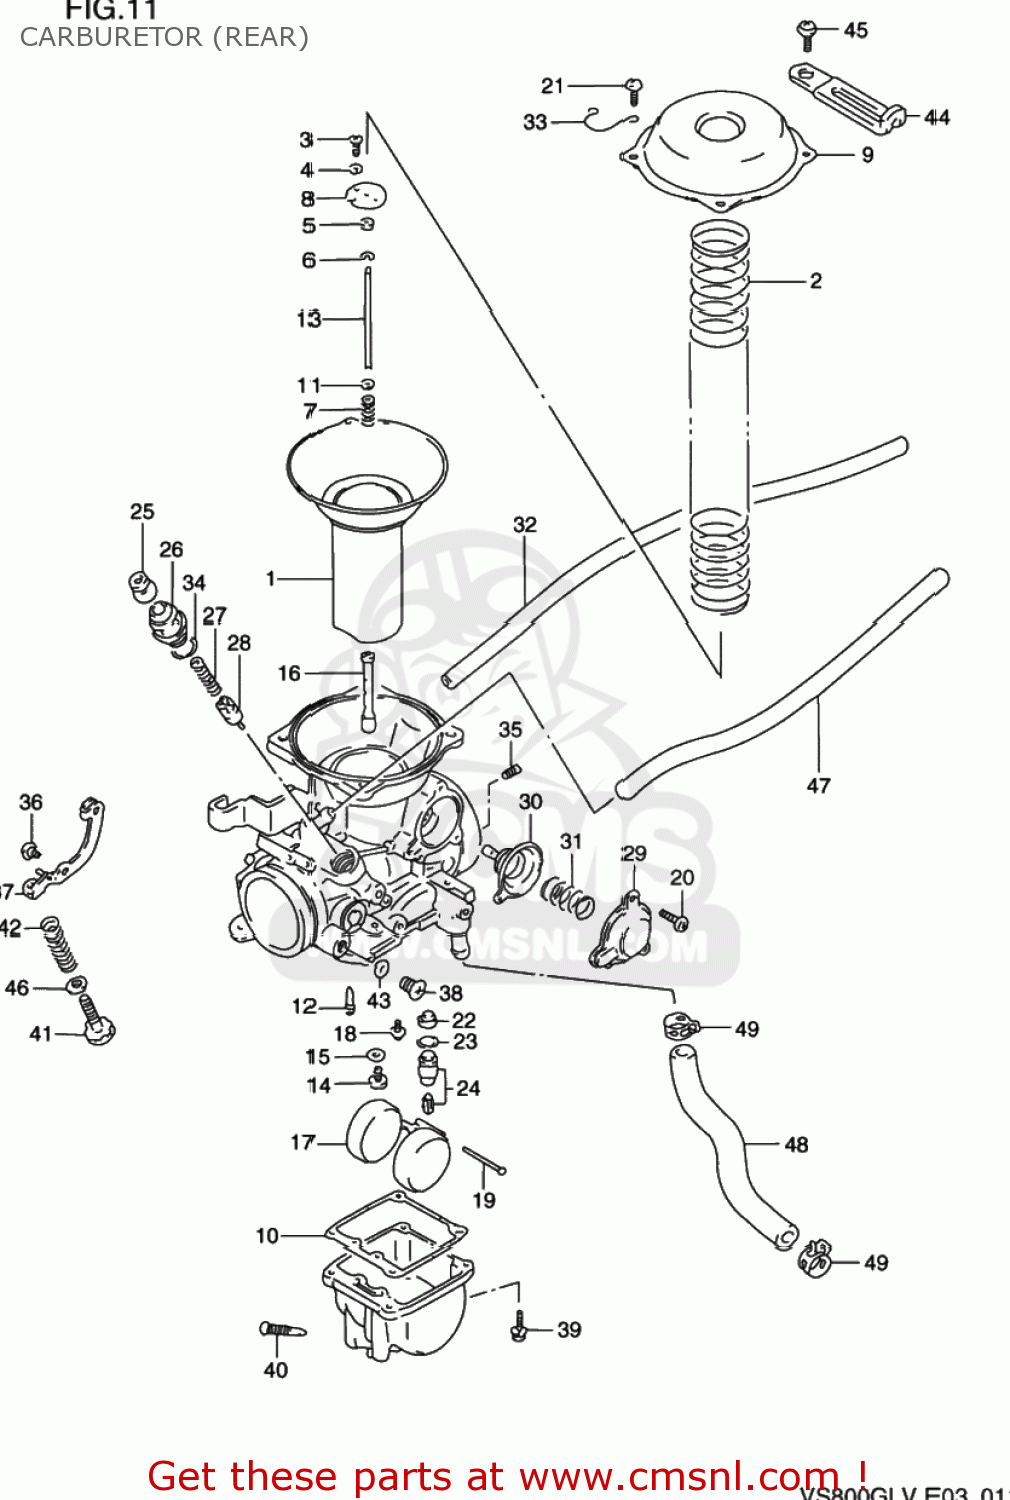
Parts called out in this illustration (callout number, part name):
1	DIAPHRAGM,CARBURETOR
2	SPRING,DIAPHRAGM
3	SCREW
4	LOCK WASHER
5	RING
6	CLIP
7	SPRING
8	PLATE
9	COVER
10	GASKET,FLOAT CHAMBER (NAS)
11	WASHER
12	JET,PILOT(45)
13	NEEDLE,JET
14	JET,MAIN(132.5)
15	WASHER,NEEDLE NOZZLE
16	JET,NEEDLE(P-7)
17	FLOAT
18	SCREW
19	PIN,FLOAT
20	SCREW
21	SCREW
22	FILTER
23	O-RING,NEEDLE VALVE
24	VALVE ASSY,NEEDLE
25	CAP
26	HOLDER,GUIDE
27	SPRING
28	PLUNGER,STARTER
29	COVER
30	DIAPHRAGM ASSY
31	SPRING
32	HOSE
33	CLIP
34	O RING
35	JET,AIR(65)
36	SCREW
37	LEVER ASSEMBLY
38	SCREW
39	SCREW
40	PLUG
41	ADJUSTER
42	SPRING
43	GASKET,DRAIN PLUG (NAS)
44	CLIP
45	SCREW
46	WASHER
47	(CA) HOSE SET,FUEL
48	HOSE
49	CLIP
